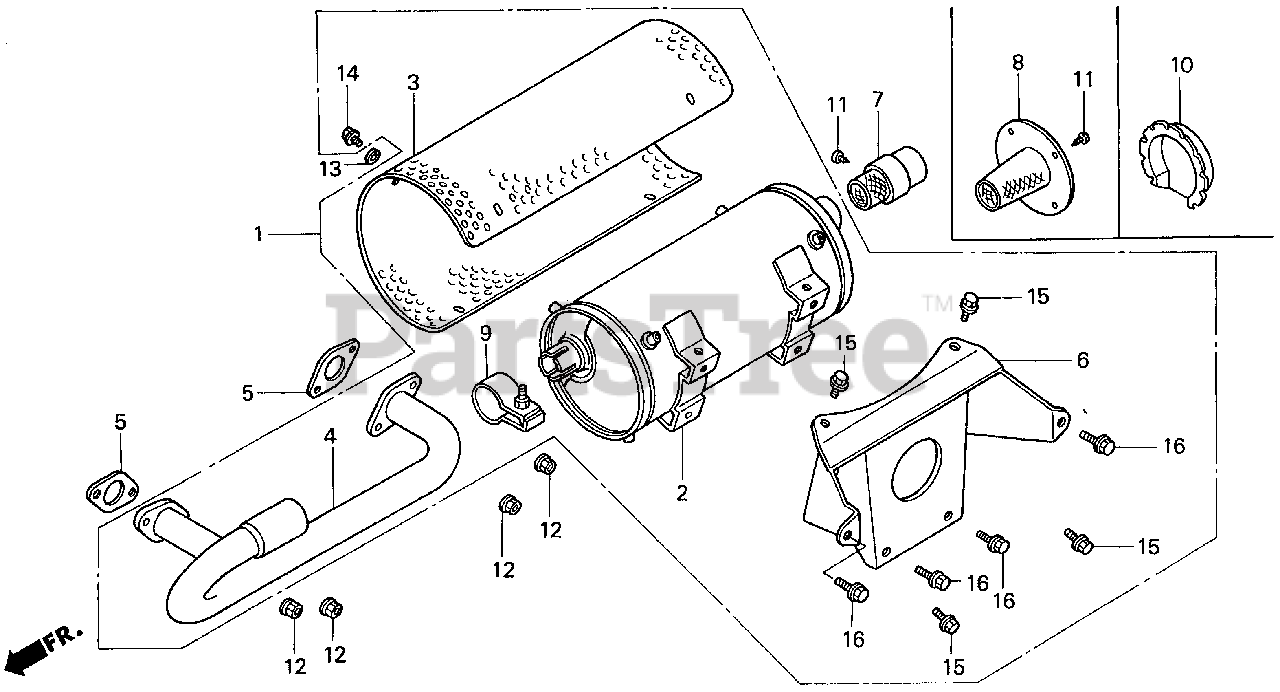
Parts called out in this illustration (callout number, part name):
1	MUFFLER KIT (HIGH-A) (N/A: SEE COMPONENTS)
2	MUFFLER (HIGH)
3	PROTECTOR, MUFFLER (HIGH)
4	PIPE, EX. (HIGH-R)
5	GASKET, EX. PIPE
6	STAY, MUFFLER (HIGH)
7	ARRESTER, SPARK
8	ARRESTER, SPARK (SIDE)
9	BAND ASSY.
10	DEFLECTOR KIT, EX.
11	SCREW (NELSON)
12	NUT, FLANGE (8MM)
13	WASHER, SPRING (6MM)
14	BOLT, FLANGE (6X8)
15	BOLT, FLANGE (8X14)
16	BOLT, FLANGE (8X20)
